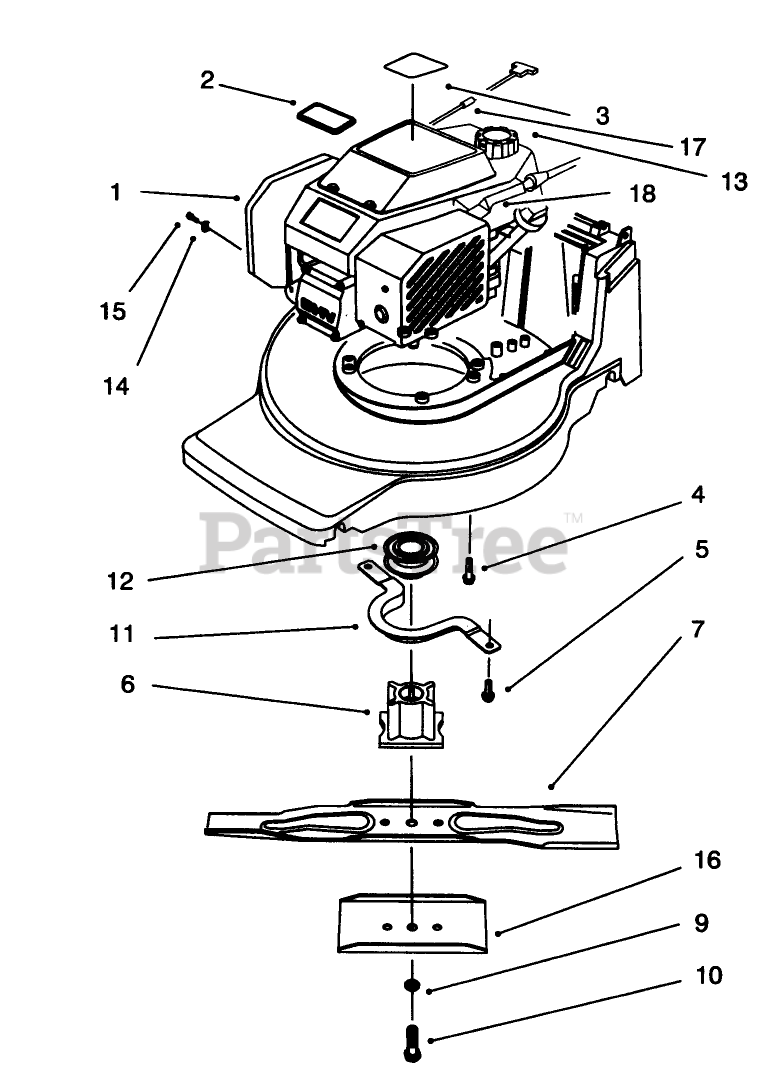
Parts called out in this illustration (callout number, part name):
1	Engine-Complete
2	PLATE-LOGO
3	DECAL - ENGINE
4	SCREW-HWH
5	SCREW-HWH
6	BLADE RETAINER - 25 MM
7	Blade
9	WASHER-LOCK
10	BOLT-BLADE
11	Guide-Belt
12	PULLEY-DRIVE, ZONE START
13	ASSEMBLY - FUEL CAP
14	CLAMP-CASING
15	CLAMP SCREW F/W ENGINE
16	Stiffener
17	STOP-ROPE
18	COVER - BRAKE F/W
